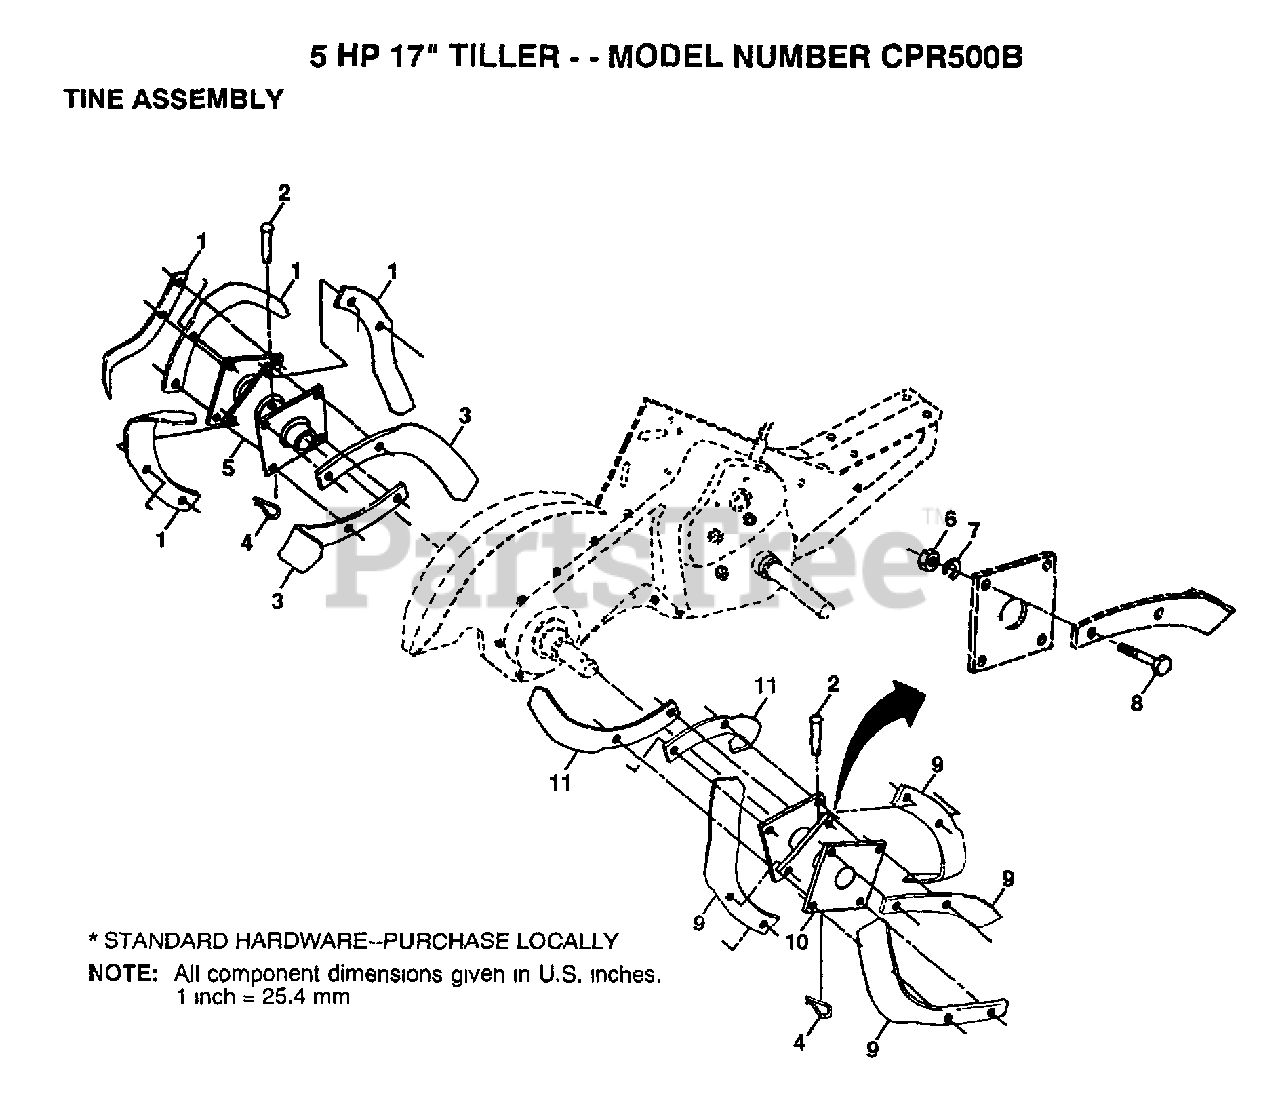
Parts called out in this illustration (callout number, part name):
2	PIN.CLEVIS.SHEAR
3	"TINE.LH.12"""
4	RETAINER.SPRING
5	HUB&PLATE ASM LH
7	LOCKWASHER
8	BOLT
10	HUB&PLATE ASM RH
11	"TINE.RH.12"""
